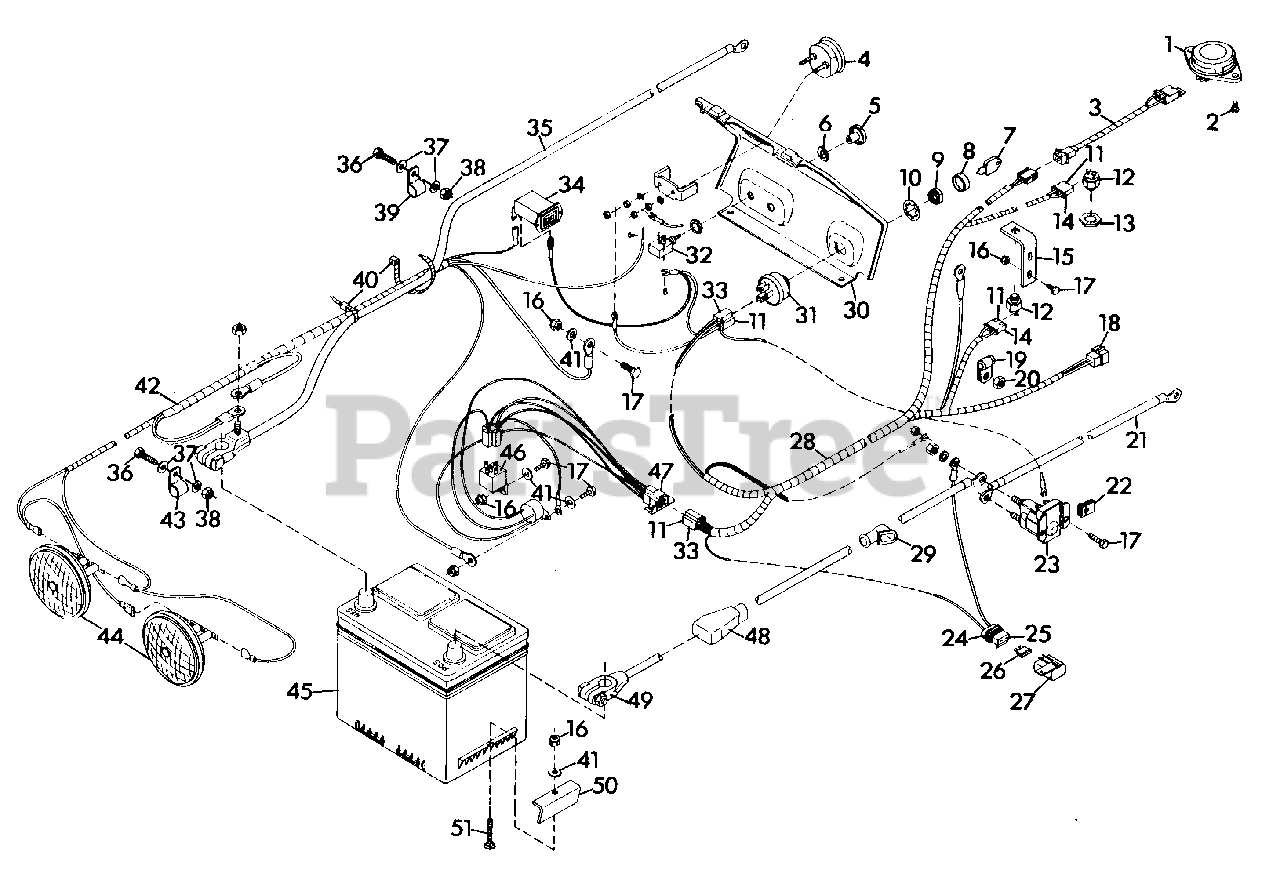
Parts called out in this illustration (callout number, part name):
1	SWITCH, SEAT
2	SCREW, MACHINE 1/4-20
3	HARNESS, WIRING SEAT SWITCH
4	GAUGE, AMMETER
5	KNOB, LIGHT SWITCH
6	NUT, SPECIAL LIGHT SWITCH
7	KEY, IGNITION SWITCH
8	BOOT, 9/16 SWITCH
9	NUT, JAM 9/16-24
10	WASHER, LOCK 9/16 INT. TOOTH
11	TERMINAL
12	SWITCH, INTERLOCK
13	NUT, STAMPED 9/16-18
14	CONNECTOR, 2-WIRE SWITCH
15	BRACKET, SWITCH
16	NUT, LOCK 1/4-20
17	BOLT, HEX 1/4-20X.75
18	CONNECTOR
19	CLAMP
20	NUT, LOCK 3/8-16
21	CABLE, STARTER
22	NUT, SPEED 1/4-20
23	SWITCH, MAGNETIC
24	CONNECTOR
25	TERMINAL, 14-16 GAUGE
26	FUSE, 25 AMP
27	COVER
28	HARNESS, WIRING
29	BOOT, BATTERY CABLE
30	PANEL, INSTRUMENT
31	SWITCH, IGNITION
32	SWITCH, LIGHT
33	CONNECTOR
34	HOURMETER
35	CABLE, NEGATIVE BATTERY
36	BOLT, HEX 5/16-18X1.00
37	WASHER, FLAT .344X.688X.065
38	CLAMP, NYLON
39	NUT, LOCK 5/16-18
40	TIE, CABLE
41	WASHER, FLAT .281X.625X.065
42	HARNESS, WIRING GROUND AND LIGHT
43	CLAMP, NYLON
44	HEADLIGHT
45	BATTERY, 12 VOLT
46	RELAY
47	MODULE, TIME DELAY
48	COVER, BATTERY TERMINAL
49	CABLE, BATTERY TO MAGNETIC SWITCH
50	CLAMP
51	BOLT, 1/4-20X1.75 RD HD SQ NK
